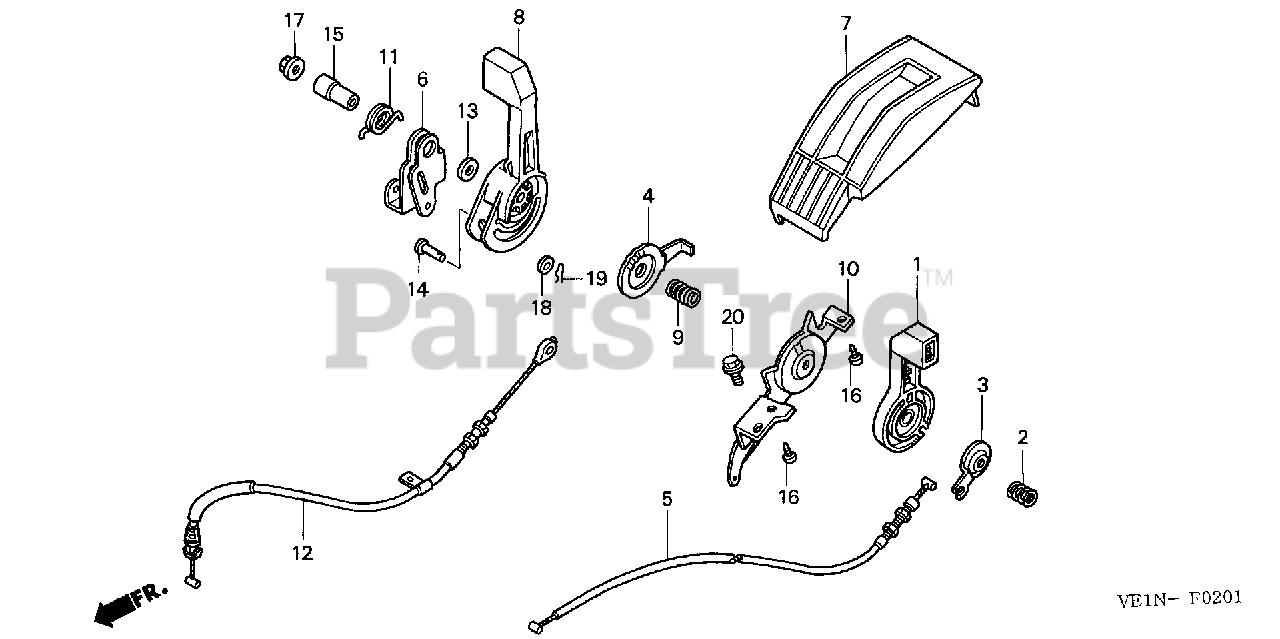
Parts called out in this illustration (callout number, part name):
1	LEVER, THROTTLE
2	SPRING, THROTTLE LEVER
3	SEAT, SPRING
4	SEAT, SPRING
5	CABLE, THROTTLE
6	ARM, CHANGE LEVER
7	COVER, CONTROL
8	LEVER, CHANGE
9	SPRING, CHANGE LEVER
10	STOPPER, LEVER
11	SPRING, ARM RETURN
12	CABLE, CHANGE (H.S.T.)
13	WASHER (10.5X30)
14	PIN (6X22)
15	COLLAR, CHANGE LEVER
16	SCREW, TAPPING (5X12)
17	NUT, FLANGE (6MM)
18	WASHER, PLAIN (6MM)
19	PIN, LOCK (6MM)
20	BOLT, FLANGE (6X10)
